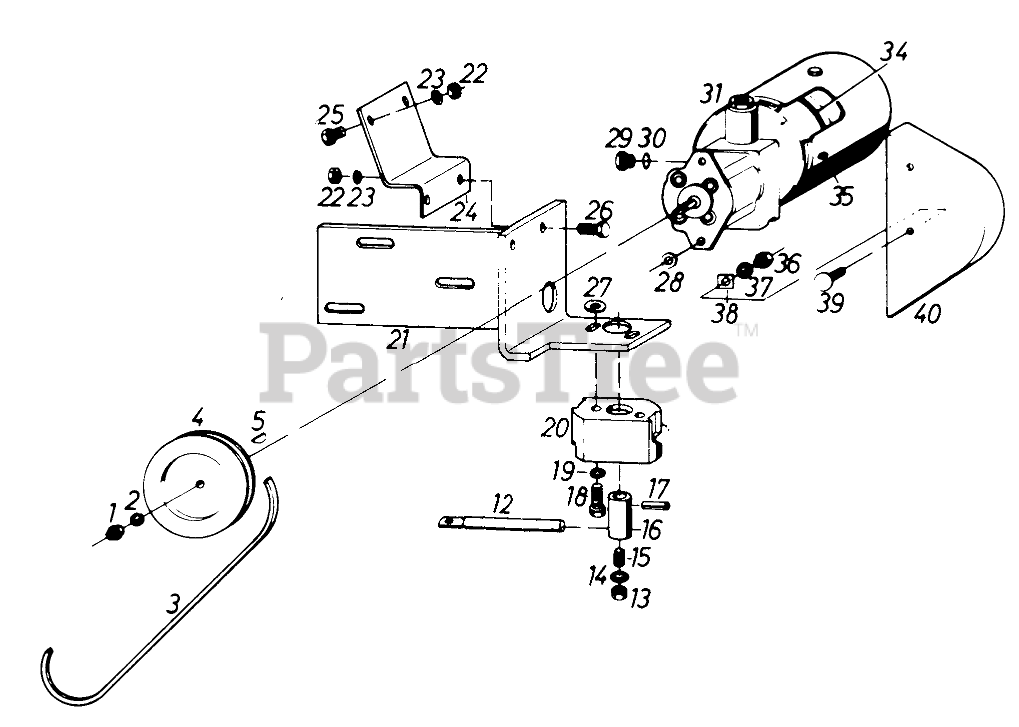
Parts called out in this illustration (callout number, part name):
2	Spring Washer
3	V-BELT 9.5 X 1175
4	Pulley
12	Lever
14	Washer
16	Bushing
19	Washer
20	Gate Assy.
21	Hydraulic Support Assy.
23	Lock Washer
24	Ignition Coil Support
25	Bolt
26	Bolt
27	Washer (4 X 20 X 0.5)
28	Washer
30	Gasket
31	Hydraulic Unit
34	Gasket
35	Screw
37	Washer
40	Protection
